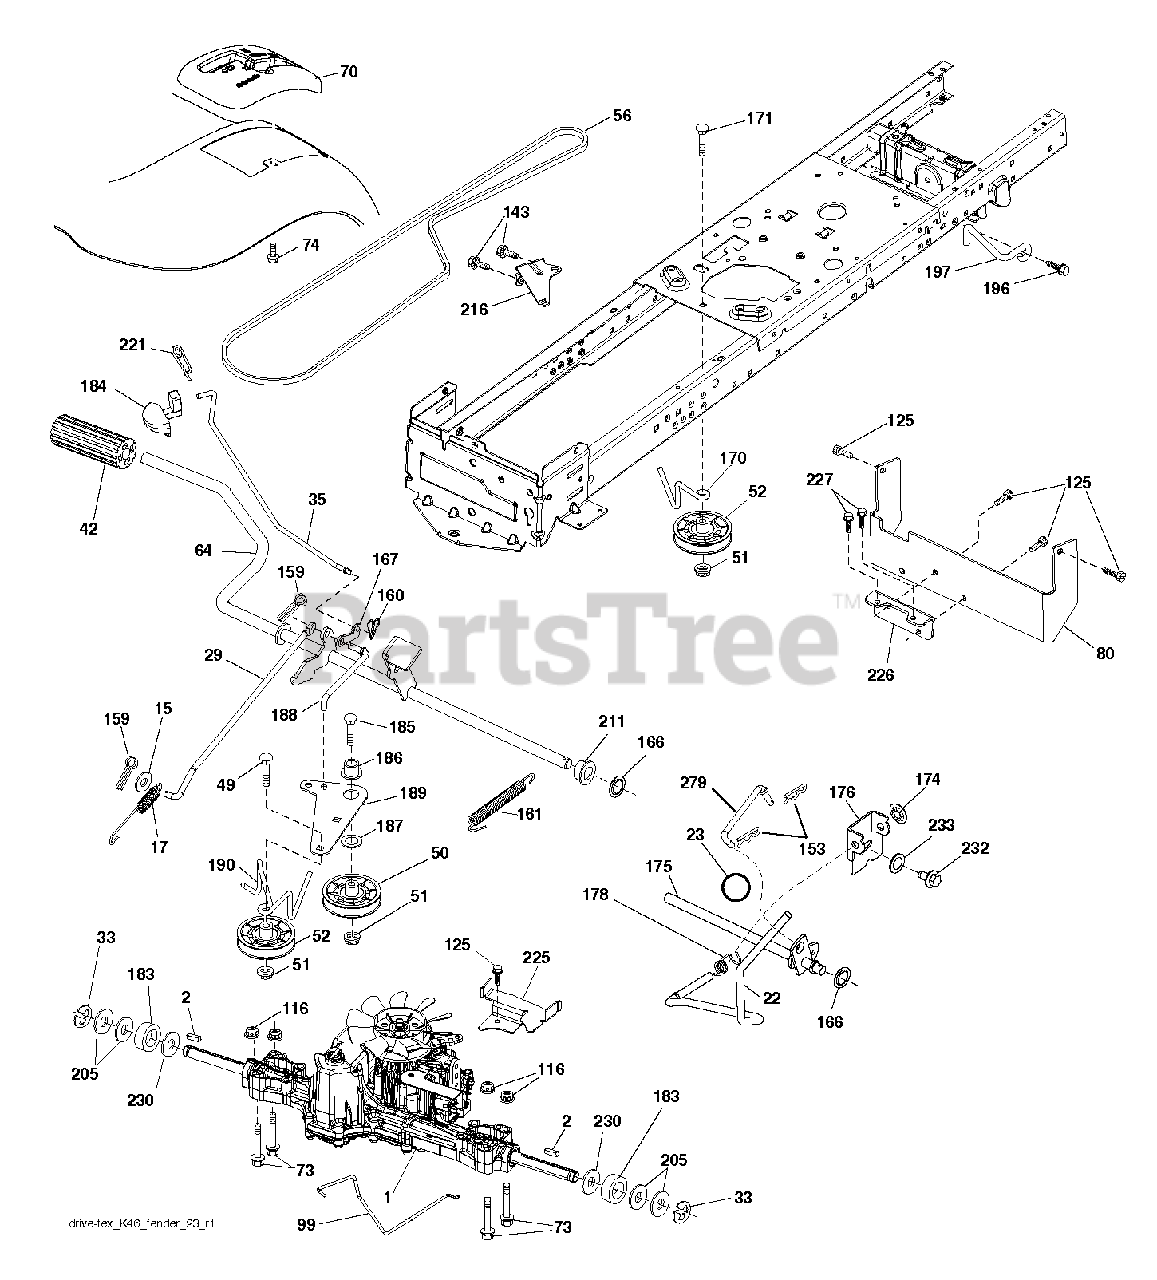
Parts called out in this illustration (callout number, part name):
2	SQUARE KEY
17	SPRING.BRAKE.K46.GREEN
22	ROD.SHIFT.FENDER.STGT.
23	PISTOL KNOB
29	ROD.BRAKE.K46
33	E-RING LT
35	ROD.BRAKE.PARKING.GT.H
42	PEDAL COVER T
49	BOLT
50	IDLER.FLAT.910.OFFSET
51	NUT LOCK FLG 3/8-16 UNC
52	IDLER.V-GROOVE.910.OFFSET
64	SHAFT.ASM.PEDAL.BRAKE.
73	BOLT HEX 5/16-18 GR 5
74	SCREW.HI-LO.CONSOLE
80	STRAP TORQUE
99	ROD.SPRING.BYPASS.K46.LT.Z
116	NUT LOCK HEX FLANGE 5/16-18
125	SCREW
153	RETAINER M
159	COTTER PIN
160	RETAINER CLIP
161	SPRING, RETURN LT
166	NUT.PUSH.625
167	LATCH.BRAKE.SPRING
170	KEEPER.V-IDLER.CENTER.
171	BOLT
174	NUT.PUSH.500.2006
175	SHAFT ASM SHIFT
176	ARM.CLEVIS.ROD.SHIFT
178	SPRING.SHIFT.GT2006
183	SPACER AXLE
184	HANDLE.PARKG.BRK.HUSQ/
186	SPACER.RETAINER
187	WASHER 12/32X2X10GA
188	LINK.CLUTCH.GROUND.DRIVE
189	BELLCRANK.GROUND.DRIVE.TEX.
190	KEEPER.BELLCRANK.DRIVE
196	SCREW 3/8-16X1
197	LINK.CLUTCH.ANIT-ROTAT
211	BUSHING.SHAFT.BRAKE.HAND
216	BRACKET.PULLEY.IDLER.W/TEX
221	RETAINER.SPRING.CLIP.H
225	KEEPER.BELT.TRANSAXLE.K46
226	BRACKET.MOUNT.TORQUE.K46.TLT
227	SCREW
230	WASHER.HARDENED
232	BOLT FIN HEX 7/16-14 X 1
233	WASHER SERRATED
279	LINK SHIFT
